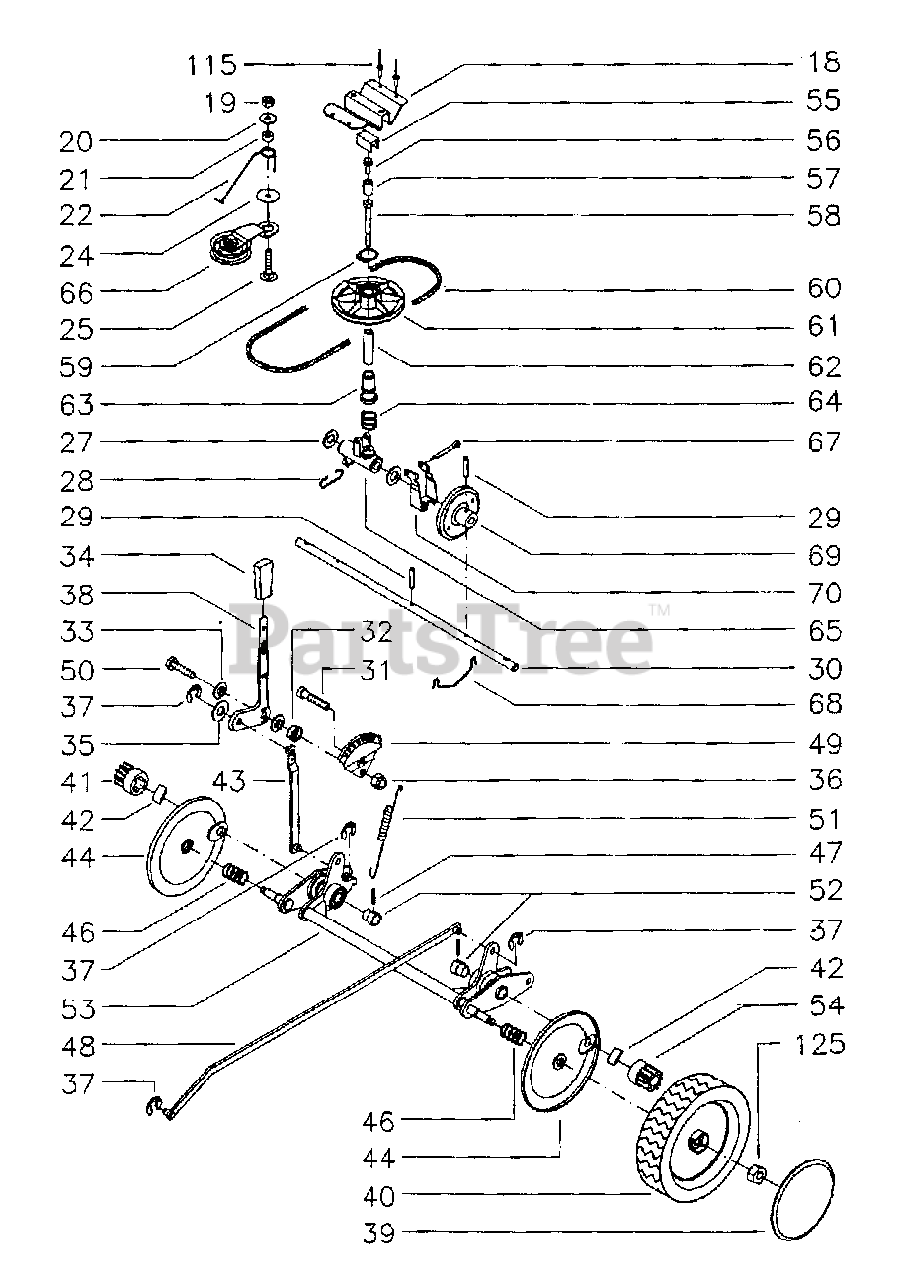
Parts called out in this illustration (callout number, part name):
19	LOCKNUT M6
27	WASHER
28	CLIPS
30	SHAFT
31	SCREW
34	PLASTIC GRIP
39	WHEEL COVER
41	PINION, RIGHT
42	CARRIER
44	SHIELD
46	SPRING
49	INDEXPLATE
54	PINION, LEFT
55	SLIDE BEARING
56	SCREW
60	BELT
61	PULLEY
63	SLEEVE
65	HOLDER
66	TENSIONER
68	HOLDER SPACER
69	WHEEL ASSY FRICTION
70	RAM
